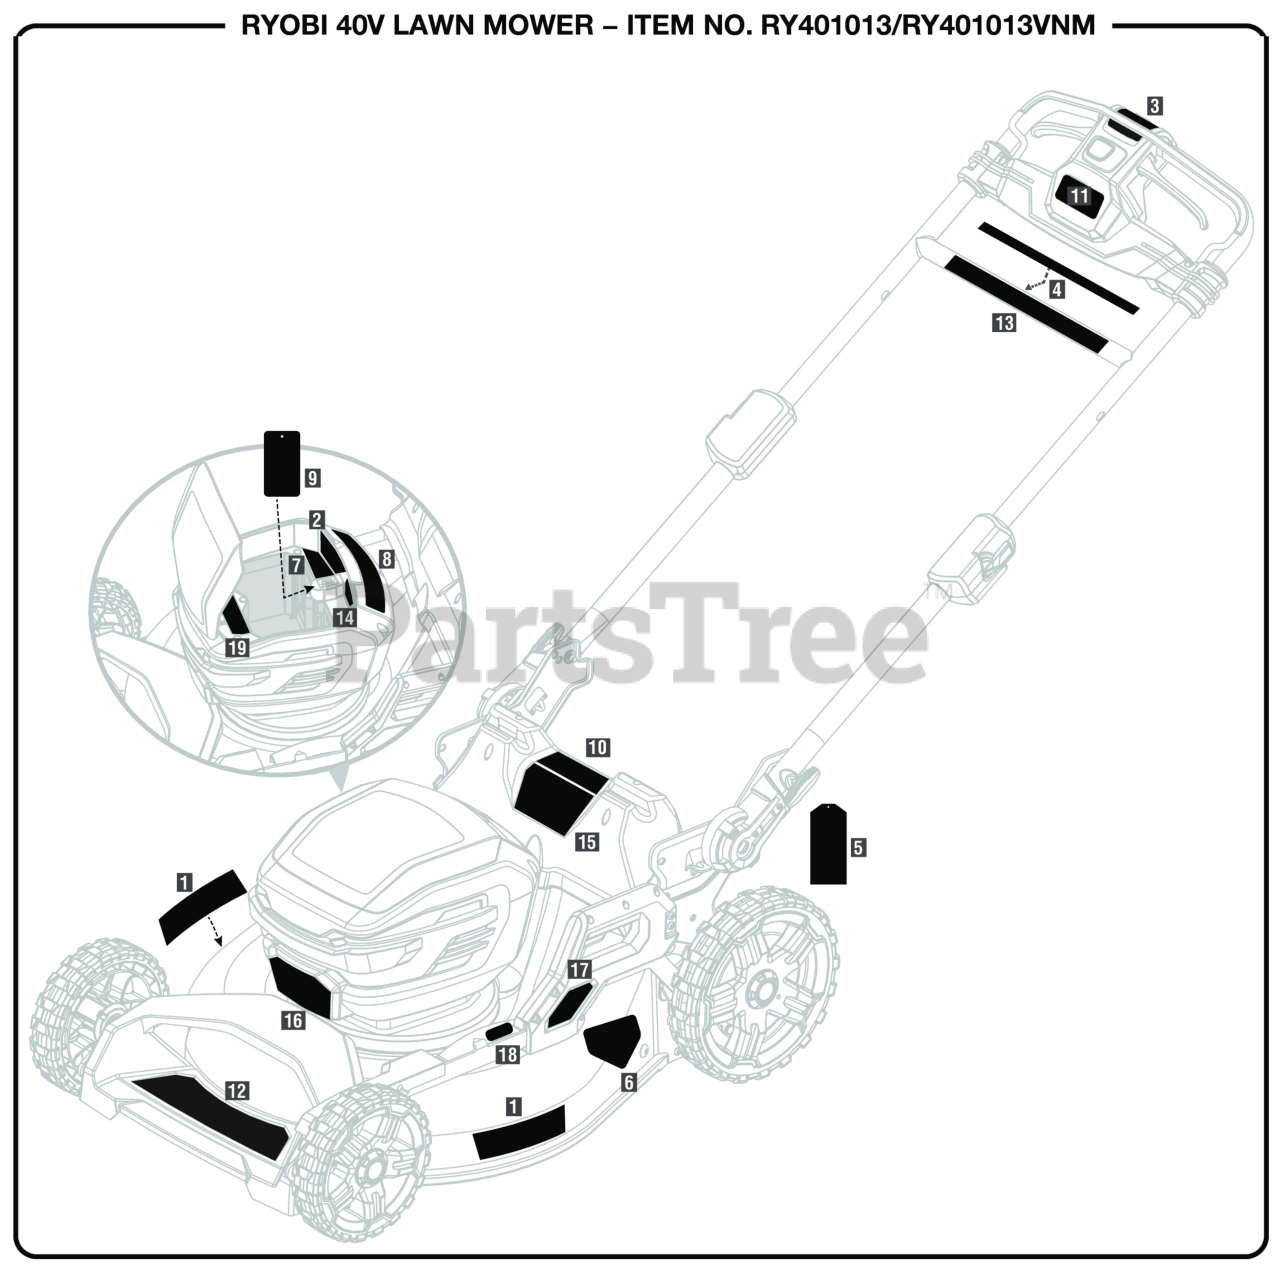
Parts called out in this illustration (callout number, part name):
1	Deck Size Label
2	Main Danger Label (SP)
3	Starting Label
4	Handles Fully Extended Label
5	Mulch Plug Hangtag
6	Danger Label (No Hands/Feet)
7	Onboard Battery Storage Label
8	Main Danger Label (EN/FR)
9	Start Key Hangtag
10	Attachment User Callout Label
11	Logo Labe
12	Self-Propelled Label
13	Handle Logo Label
14	Start Key Warning/Data Combo Label
15	Guard Warnings Label
16	Logo Label (Front)
17	Single Point Adjust Label
18	Cut Height Label
19	Battery Wet Conditions/Data Label (RY401013)
